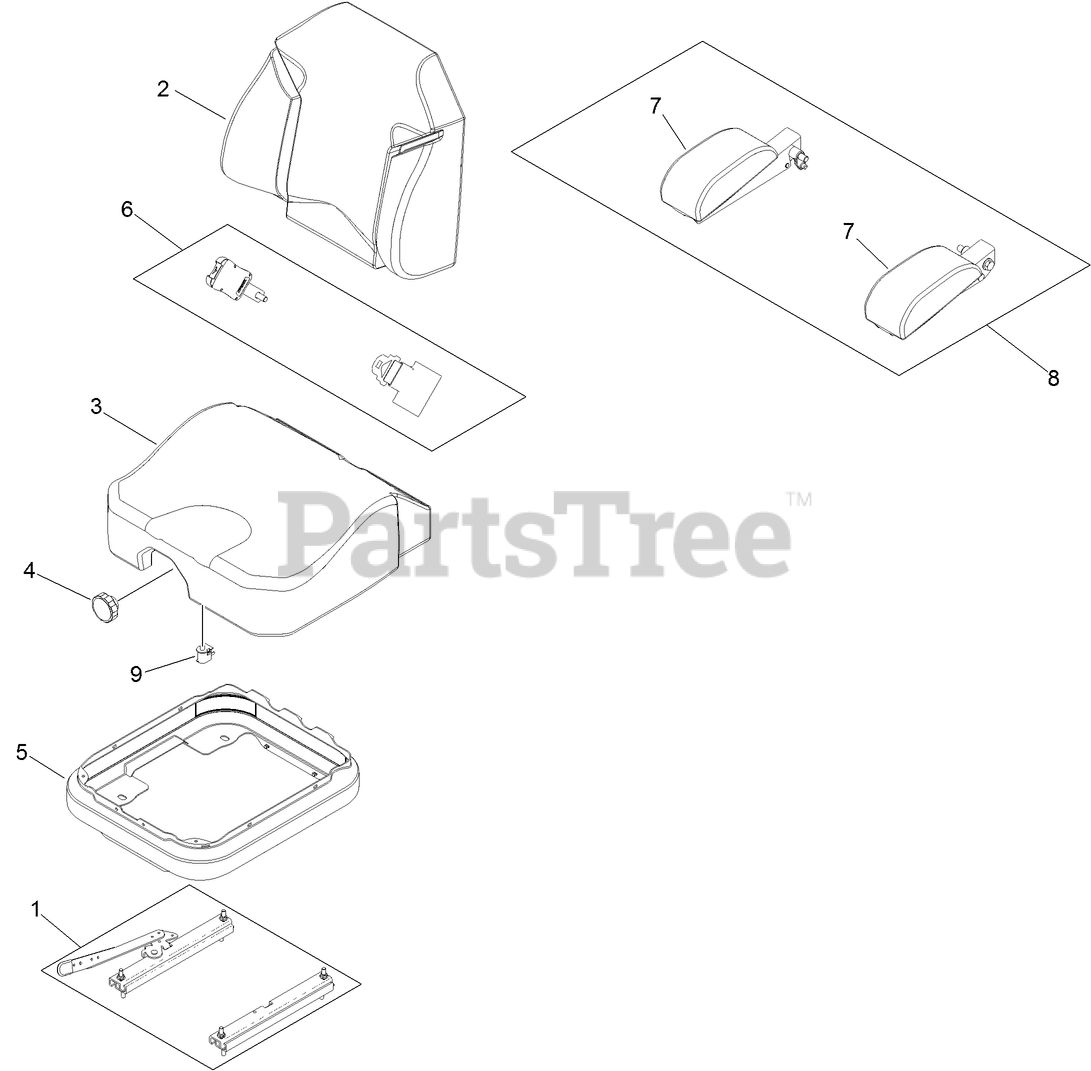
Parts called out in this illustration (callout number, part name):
1	SEAT TRACK SET
2	COVER-BACK
3	COVER-CUSHION
4	Knob-Adjuster
5	COVER-SUSPENSION, BELLOWS
6	SEAT BELT KIT
7	ARM REST PAD SET
8	ARM REST SET
9	SWITCH-BAIL
